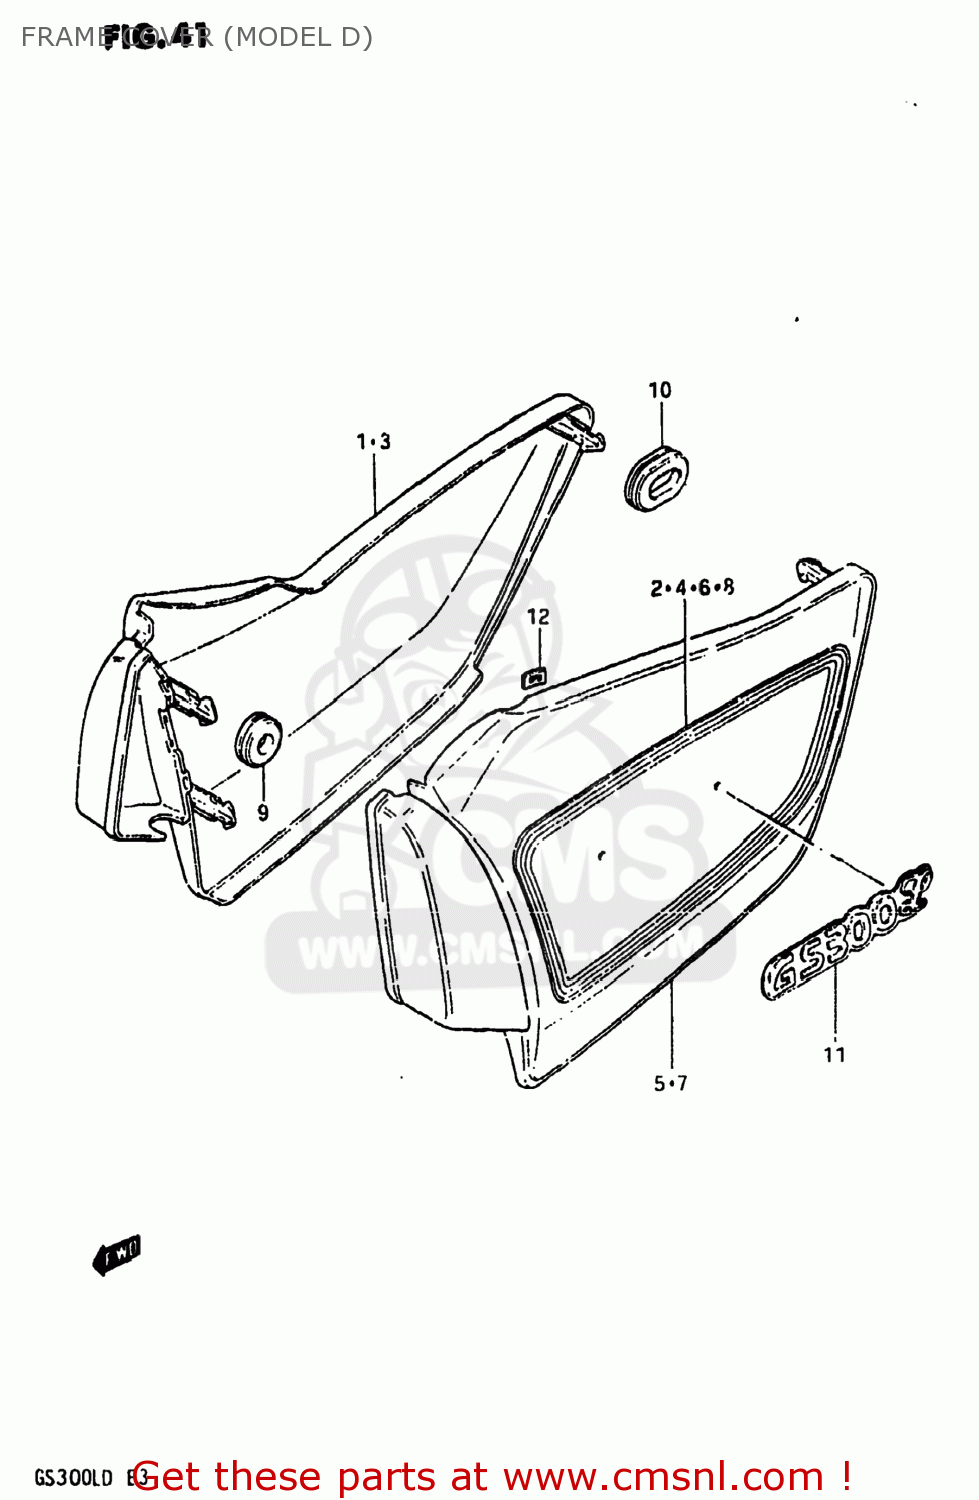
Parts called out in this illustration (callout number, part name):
1	COVER,FRAME,RIGHT
2	TAPE SET,FRAME COVER
3	COVER,FRAME,RIGHT
4	TAPE SET,FRAME COVER
5	COVER,FRAME,LEFT
6	TAPE SET,FRAME COVER
7	COVER,FRAME,LEFT
8	TAPE SET,FRAME COVER
9	CUSHION
10	CUSHION
11	EMBLEM,FRAME COVER
12	NUT
